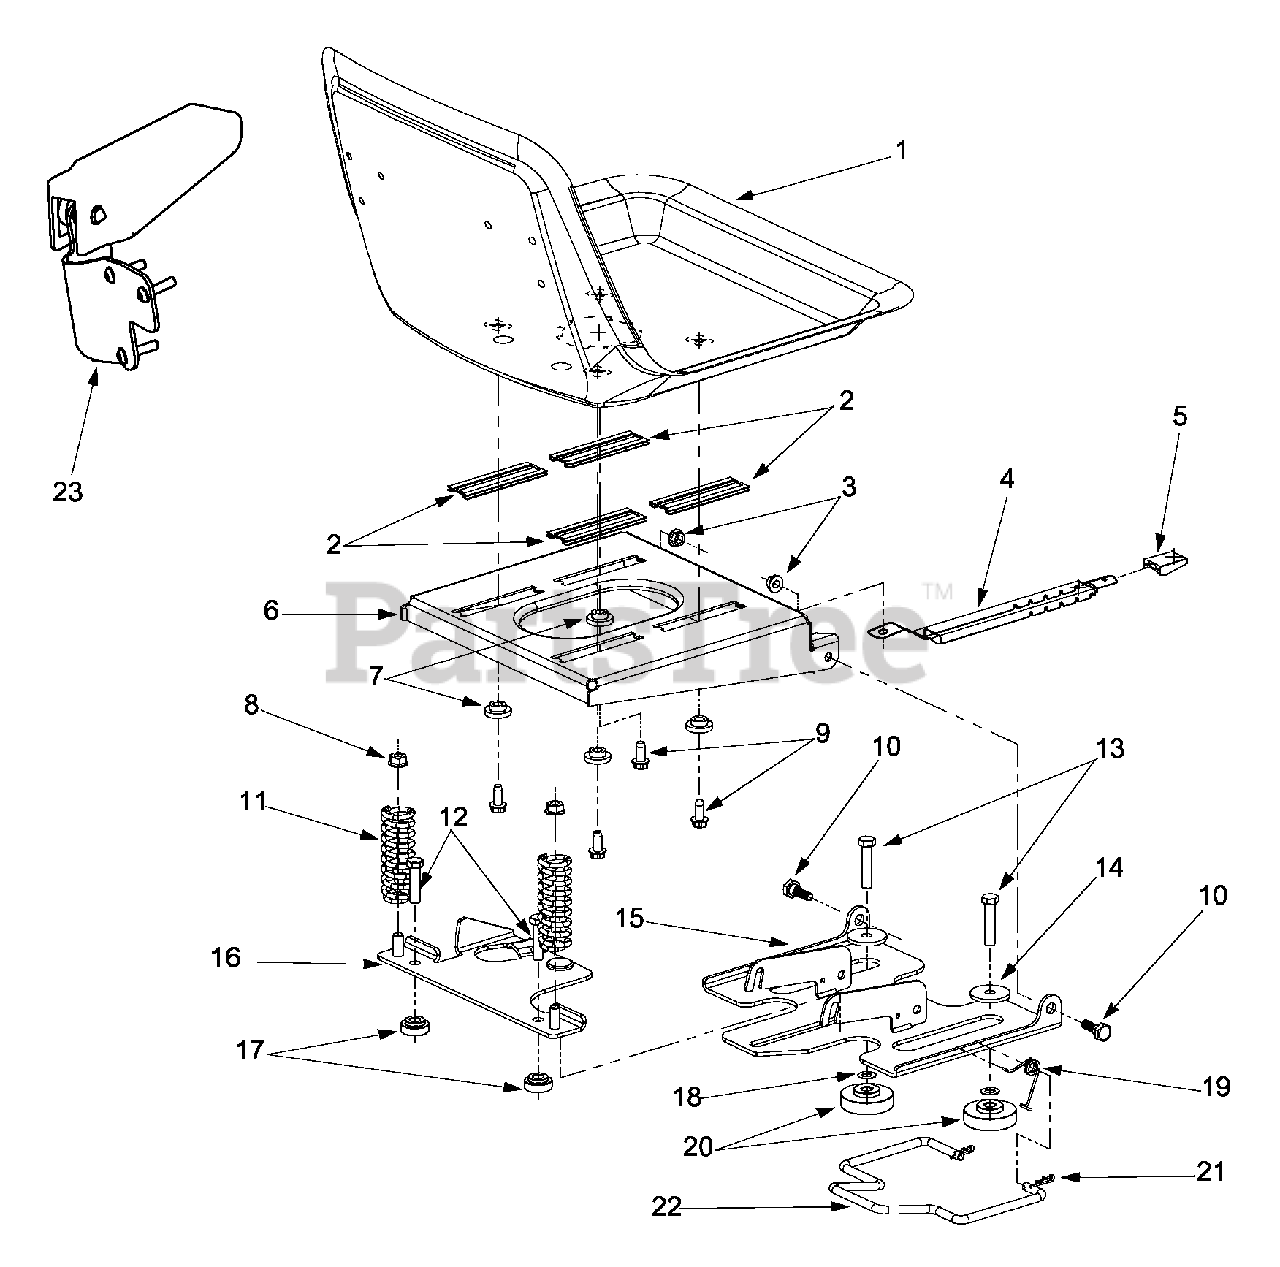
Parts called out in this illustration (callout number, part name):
1	Seat Assembly
3	Flange Lock Nut 5/16-18
4	Spring Index
5	Knob
8	Flange Lock Nut 3/8-16
9	Hex Washer Screw 5/16-18 x .75
10	Shoulder Screw
11	Compression Spring 1.28 OD x 3.5
12	Hex Cap Screw 3/8-16 x 1.5
13	Hex Cap Screw 3/8-16 x 1.75
18	Thrust Washer
19	Torsion Spring
20	Shoulder Spacer
23	Seat Arm (Set of Two)
